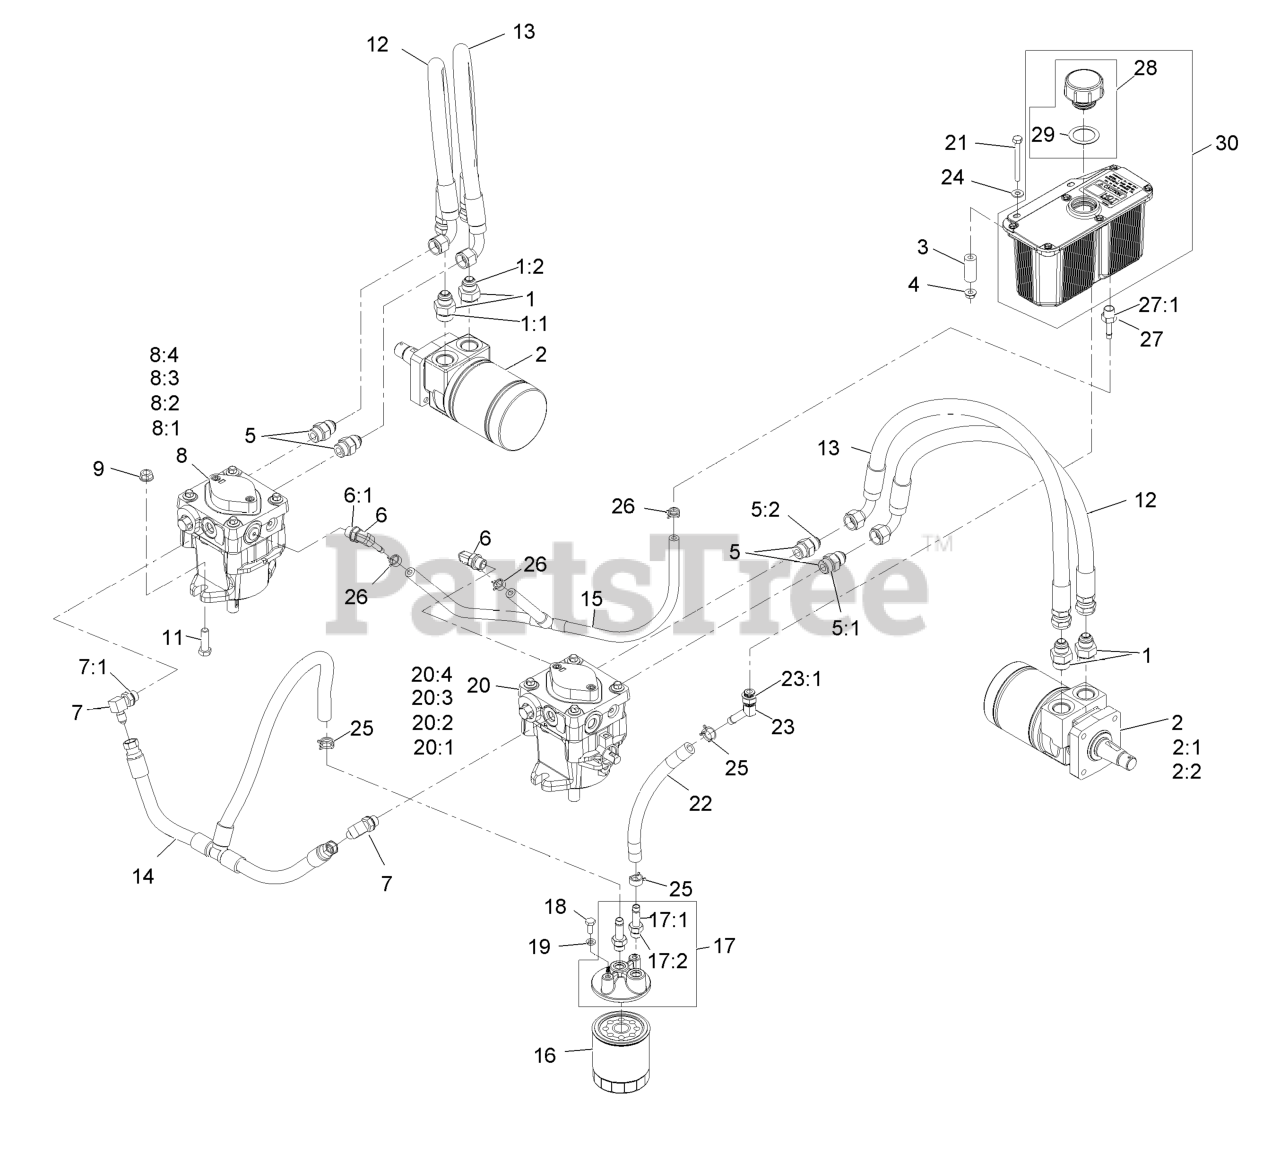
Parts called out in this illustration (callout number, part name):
1	FITTING-STRAIGHT
2	HYD MOTOR ASM
2:1	BEARING AND SEAL KIT
2:2	SEAL KIT
5	FITTING-STRAIGHT
6	ELBOW-90 DEG
7	FITTING-ELBOW, 90 DEG
8	LH HYD PUMP ASM
8:1	INPUT SHAFT KIT
8:2	BEARING-THRUST
8:3	CYLINDER BLOCK KIT
8:4	SEAL OVERHAUL KIT
9	NUT-FLANGE
11	SCREW-HH
12	HYD HOSE ASM
13	HYD HOSE ASM
14	CHARGE HOSE ASM
15	CASE DRAIN HOSE ASM
16	FILTER-25 MICRON, BI-DIRE
16	ELEMENT-FILTER, WINTER
17	FILTER HEAD ASM
17:1	ADAPTER-STRAIGHT
18	SCREW-HH
19	WASHER-LOCK
20	RH HYD PUMP ASM
20:1	INPUT SHAFT KIT
20:2	BEARING-THRUST
20:3	CYLINDER BLOCK KIT
20:4	SEAL OVERHAUL KIT
21	SCREW-HH
22	HOSE-CHARGE
23	FITTING-BARBED, 45 DEG
24	WASHER-FLAT
25	CLAMP-HOSE
26	CLAMP-HOSE
27	ADAPTER-STRAIGHT
28	KIT,HYD RES CAP W/GASKET
29	GASKET-CAP
30	HYD RESERVOIR ASM
